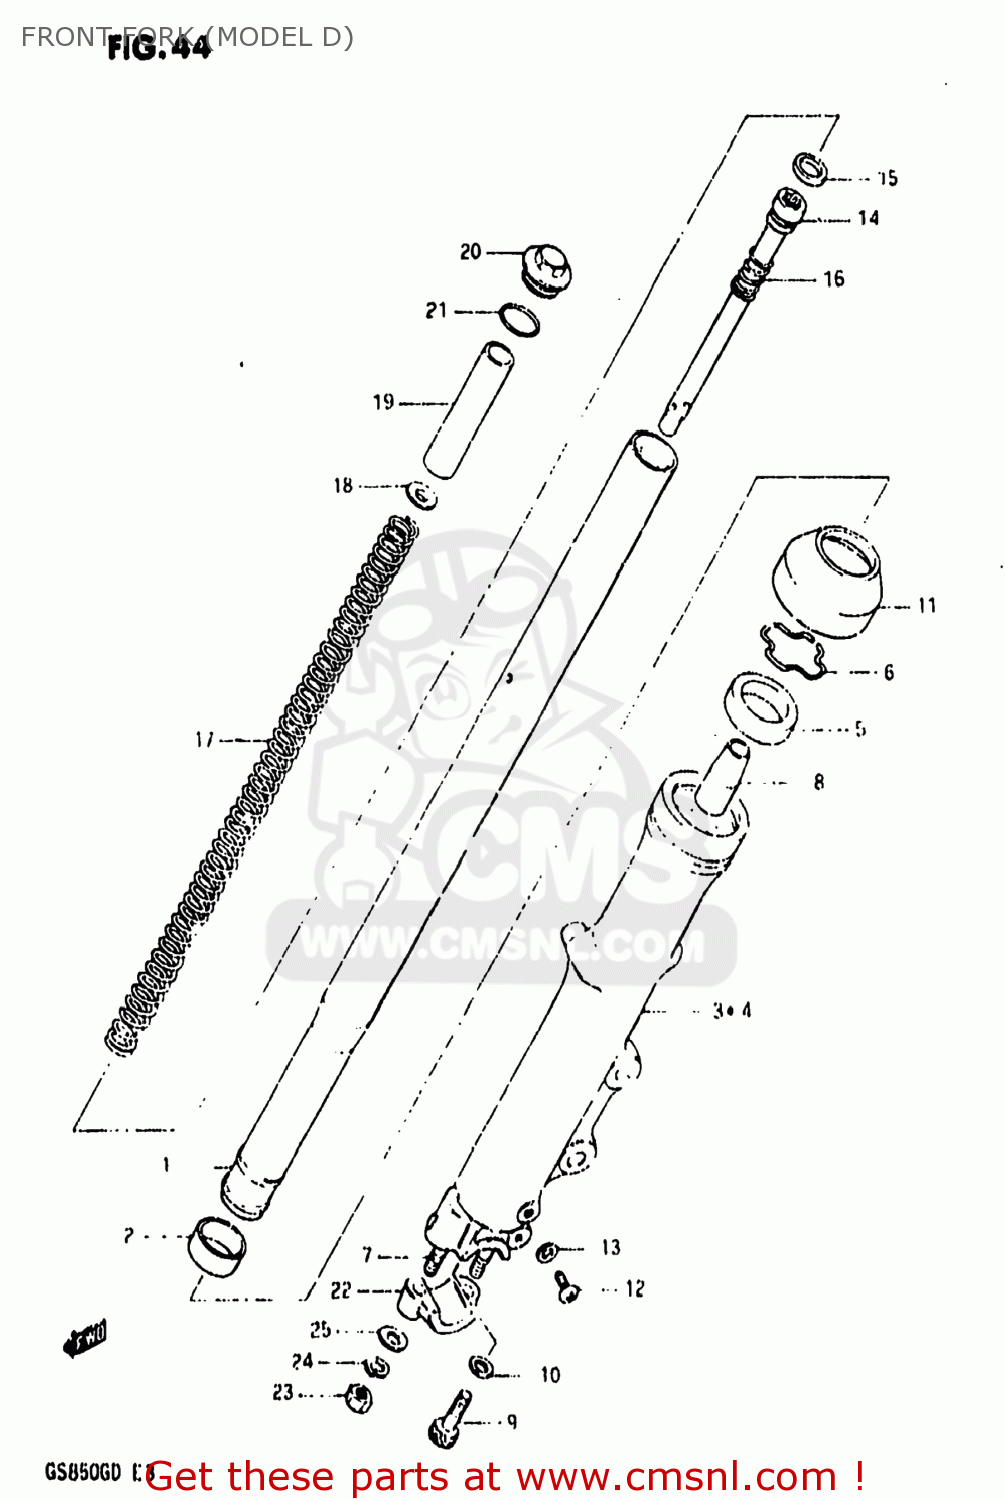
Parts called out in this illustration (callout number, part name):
0	DAMPER ASSEMBLY,LEFT
1	TUBE,FORK,INNER
2	PISTON
3	TUBE,FORK,OUTER,RIGHT
4	TUBE,FORK,LEFT,OUTER
5	OIL SEAL,FRONT FORK
6	RING,STOPPER
7	STUD 8X30
8	PIECE,OIL LOCK
9	BOLT,FORK CYLINDER(10X25)
10	GASKET (NAS)
11	SEAL,DUST
12	SCREW
13	GASKET,DRAIN,PLUG (NAS)
14	CYLINDER,FRONT FORK
15	RING,PISTON
16	SPRING,REBOUND
17	SPRING,FRONT FORK
18	GUIDE,FRONT FORK SPRING C
19	SPACER,SPRING
20	CAP,FORK INNER TUBE
21	O RING
22	HOLDER,AXLE
23	NUT (8MM)
24	LOCK WASHER
25	WASHER
